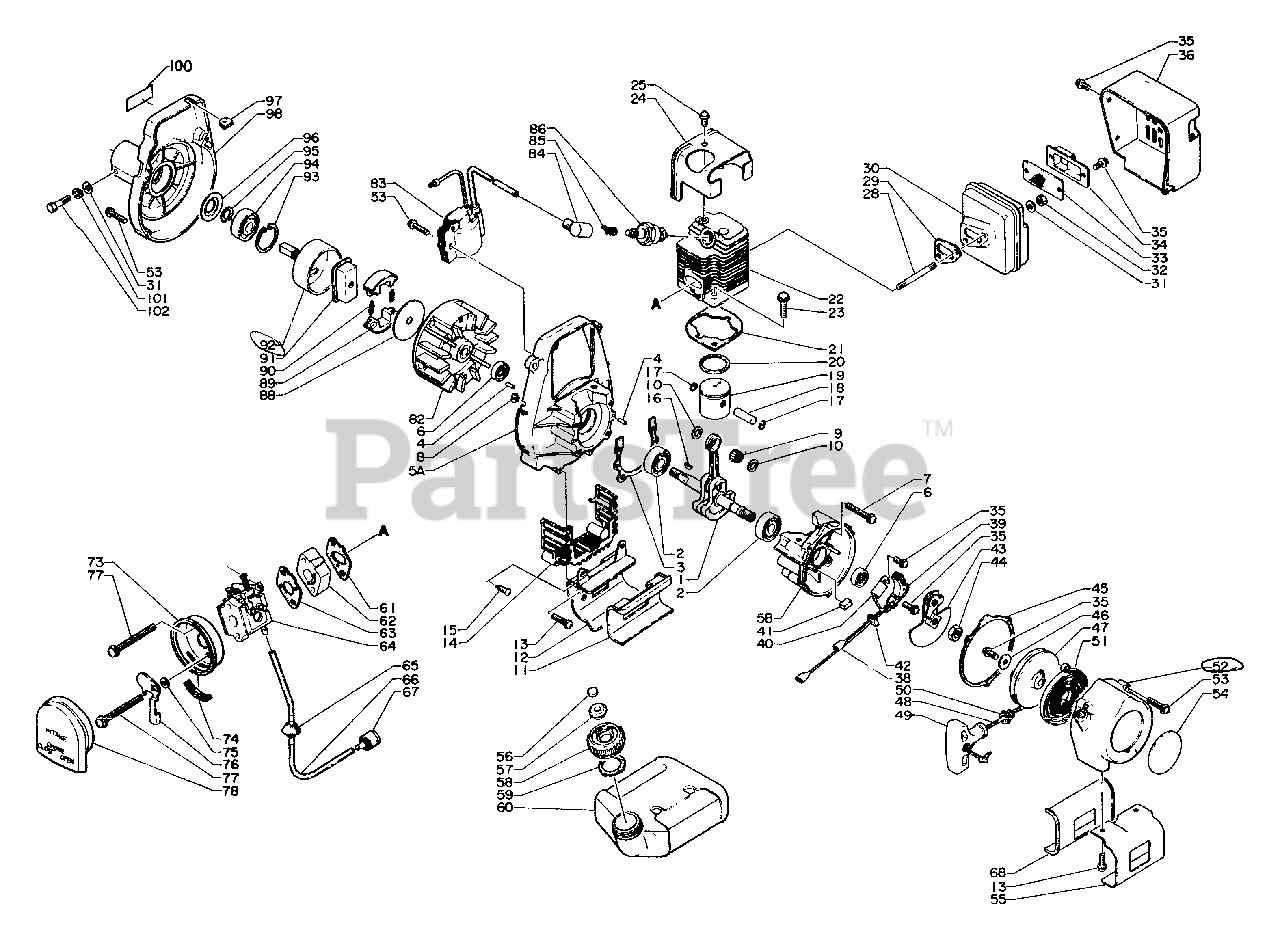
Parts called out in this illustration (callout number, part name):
1	CRANKSHAFT ASSY
2	BEARING, BALL - 6200
3	GASKET, CRANKCASE
4	PIN - LOCATING
5	CRANKCASE KIT
5A	CRANKCASE KIT
5B	CRANKCASE KIT
6	SEAL, OIL
7	SCREW - 5X30
9	BEARING, NEEDLE - 8
10	SPACER, PISTON
11	CUSHION
12	BRACKET, FUEL TANK
13	SCREW - 4X14
14	SEAL, DUST
15	SCREW - 4X14 -- TAPPING
17	RING, RETAINING
18	PIN, PISTON
19	PISTON
20	RING, PISTON
21	GASKET, CYLINDER
22	CYLINDER
23	SCREW - 6X22
24	COVER, ENGINE
25	SCREW - 5X10
29	GASKET, EXHAUST
30	MUFFLER
31	WASHER - 5
32	LOCKNUT - 5
33	SCREEN, SPARK ARRESTOR
34	GUIDE, EXHAUST
35	SCREW - 4X10
36	COVER, MUFFLER
38	LEAD - GROUND
39	CONTACT POINT SET
40	CONDENSER
41	PAD, OIL
43	STARTER PAWL ASSY
45	GASKET, STARTER
47	REEL, ROPE
48	ROPE, STARTER - 3X850
49	GRIP, STARTER
50	GUIDE, ROPE
51	SPRING, REWIND
52	CASE, STARTER
53	SCREW - 4X20
54	LABEL - ECHO
55	BRACKET, FUEL TANK
58	CAP
59	GASKET, CAP
60	TANK, FUEL
61	GASKET, INTAKE
62	INSULATOR, INTAKE
63	GASKET, INTAKE
64	CARBURETOR WA-81
66	PIPE - 3X5X150 -- BLACK
67	FILTER, FUEL
68	CUSHION
73	CASE, AIR FILTER
75	WASHER - 5
76	SHUTTER, CHOKE
77	SCREW - 5X57
78	FILTER, AIR
82	FLYWHEEL
83	COIL, IGNITION
84	CAP, SPARK PLUG
85	TERMINAL, SPARK PLUG CAP
86	SPARK PLUG -- CJ-8
88	PLATE, CLUTCH
89	SHOE, CLUTCH
90	SPRING, CLUTCH
91	HUB, CLUTCH
92	DRUM, CLUTCH
93	RING, RETAINING - 32
94	BEARING, BALL - 6201
95	RING, RETAINING - 12
96	RETAINER, PIPE
98	CASE, STARTER
100	LABEL
101	LOCKWASHER - 5
102	BOLT - 5X25
